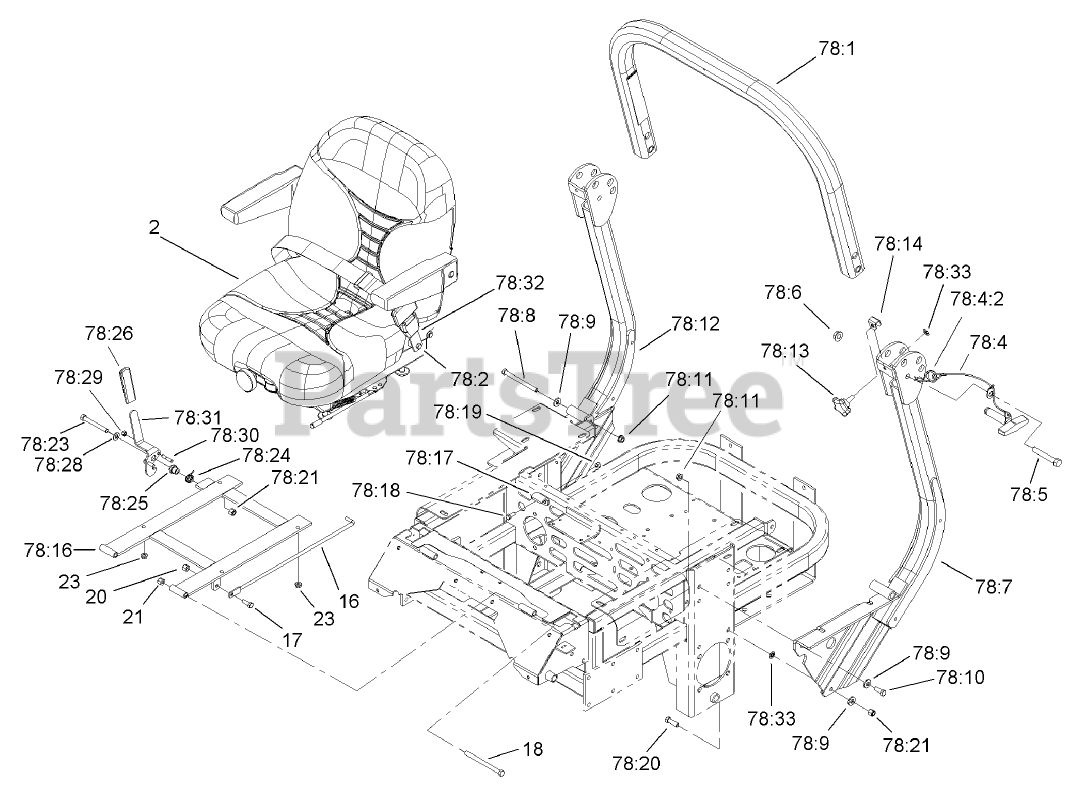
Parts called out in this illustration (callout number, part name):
2	SEAT-SUSPENSION
16	ROD-HOLDUP, SEAT
17	SCREW-HH
18	SCREW-HH
20	NUT-LOCK, NI
21	NUT-LOCK, NI
23	NUT-HF
78	ROPS ASM
78:1	Upper Tube ASM
78:2	SCREW-HH
78:3	NUT-LOCK
78:4	PIN LATCH ASM
78:4:2	Hairpin
78:5	SCREW-HH
78:6	NUT-HF
78:7	LH Rops ASM
78:8	SCREW-HH
78:9	WASHER-BELLEVILLE
78:10	SCREW-HH
78:11	NUT-HHF, WHIZ
78:12	RH Rops ASM
78:16	SEAT SUPPORT FRAME ASM
78:17	Catch-Latch, Seat
78:18	SCREW-HH
78:19	NUT-LOCK, NI
78:20	SCREW-HH
78:21	NUT-LOCK, NI
78:23	SCREW-HH
78:24	SPRING-TORSION
78:25	BUSHING-LATCH, SEAT
78:26	GRIP-HANDLE
78:28	WASHER-FLAT
78:29	NUT-LOCK, NI
78:32	Belt-Seat
78:33	NUT-PUSH
